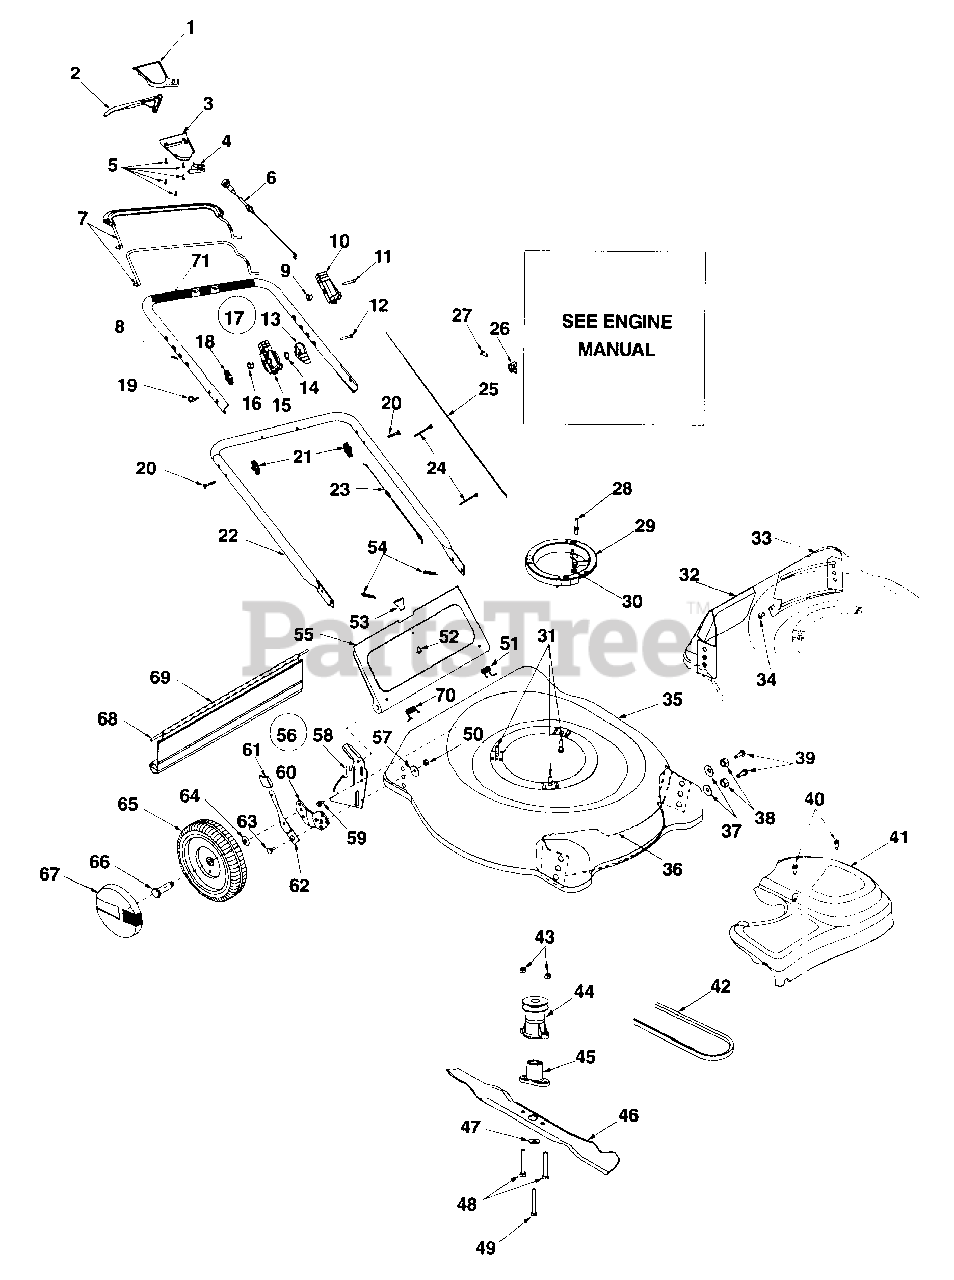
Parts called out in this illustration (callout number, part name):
1	Upper Drive Cover
2	Drive Lever
3	Lower Drive Cover
4	Mounting Cap
5	Screw #10-12:75
6	Drive Cable
10	Control Hsg.
11	Scr. Oval C-Sunk 1/4-20 x 1.31
12	Scr. Oval C-Sunk 1/4-20 x 1.81
13	Throttle Lever
14	Curved Washer .663 x .980 x .014
15	Throttle Housing
16	Hex Lock Nut 1/4-20 Thd.
17	Throttle Body Comp.
19	Eye Bolt 1/4-20
20	Carriage Bolt 5/16-18 x 2.0
23	Throttle Cable: 55" (B&S)
24	Tie Cable
25	Control Cable 39" (B&S)
26	Cable Clamp (B&S)
27	Hex Screw: T: #10-32 (B&S)
28	Pin-Belt Keeper
29	Engine Spacer
30	Hex Nut 1/4-20 Thread
31	Tapp Screw w/ Hex Lock Wash
34	Scr. AB: 1/4-14 .625 Trust
38	Bell Washer .39 x 1.13 x .062
39	Hex Screw 3/8-16 x .75
40	Screw #12 x .457
41	Trans Cover - Black
42	V-Belt
43	Hex Lock Nut 1/4-20
44	Drive Pulley
45	Blade Adapter
46	21" Mulching Blade w/star
47	Bell Washer .396 I.D. x 1.140 O.D. x
48	Hex Screw 1/4-2 Ox 1.50
49	Hex Screw 3/8-24 x 2.50
50	Hex Nut 3/8-16
51	Torsion Spring L.H.
52	Scr. Tr. Mach #10-24 x .380
54	Cotter Pin
58	Handle Brkt Ass'y - LW
59	Hex Screw w/wsh. 1/4-14 x .62
60	Pivot Bar - LH
61	Knob
62	Spring Lever
63	Shldr Screw .500 Dia x .434 Long
64	Bell Washer .380 x .880 x .062
65	Wheel 8 x 1.75 Disk Bar Grey
66	Shldr Screw .498 x 1.445
67	Hubcap: Euro Grey 3 1/2"
68	Wire
69	Rear Flap
70	Torsion Spring R.H.
71	Foam Grip
